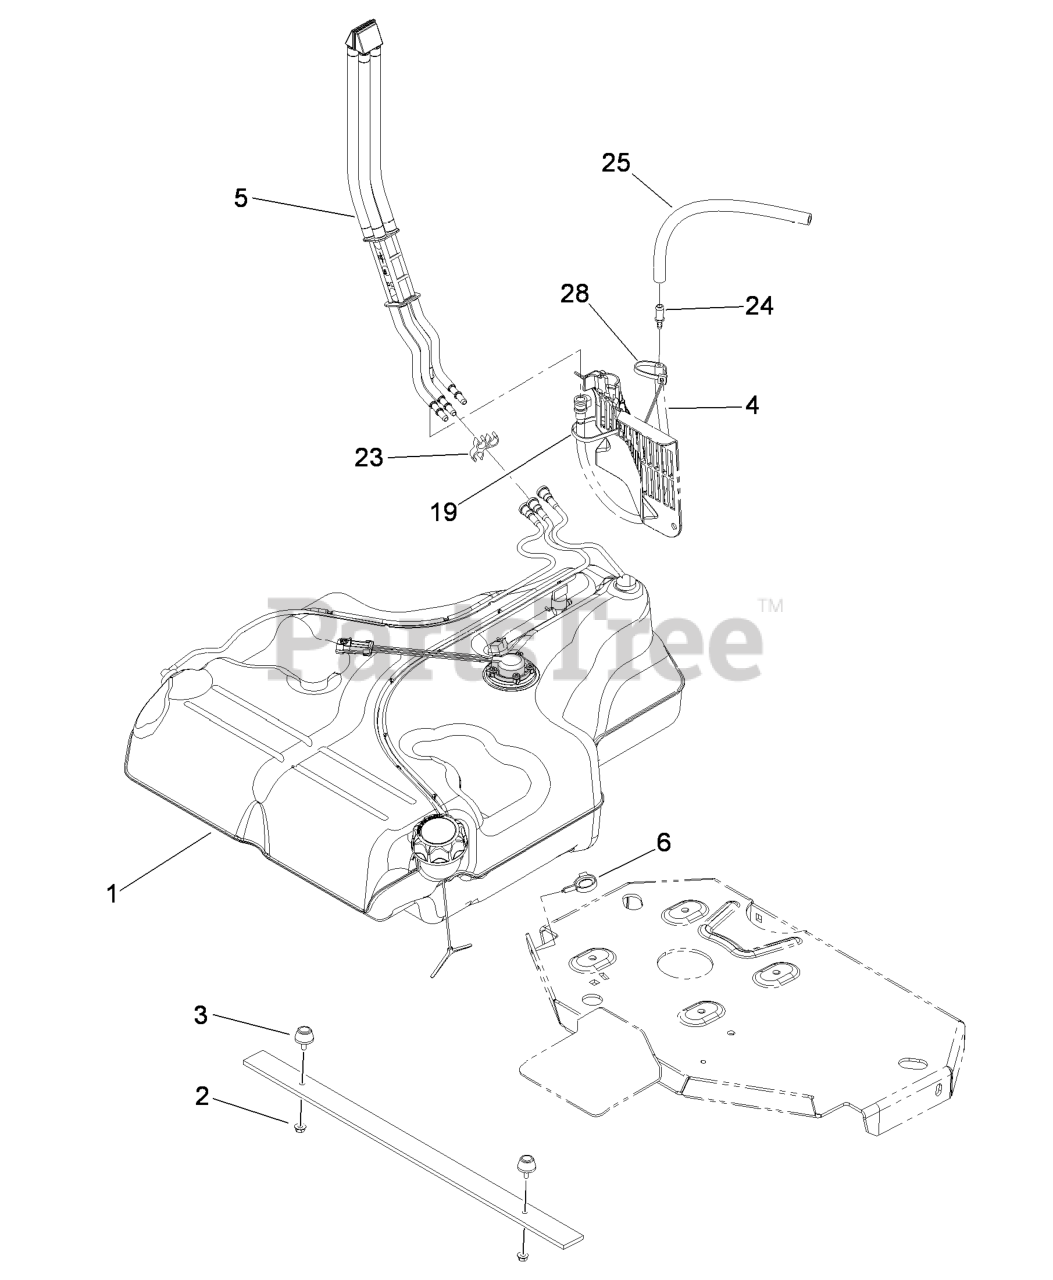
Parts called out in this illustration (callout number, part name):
3	BUMPER-RUBBER
4	HOSE ASM
5	FUEL MANIFOLD VENT ASM
6	CLAMP-HOSE
19	TIE-PLASTIC
23	CLIP-SPACER
24	FITTING-STRAIGHT
25	HOSE-FUEL
28	TIE-PLASTIC
